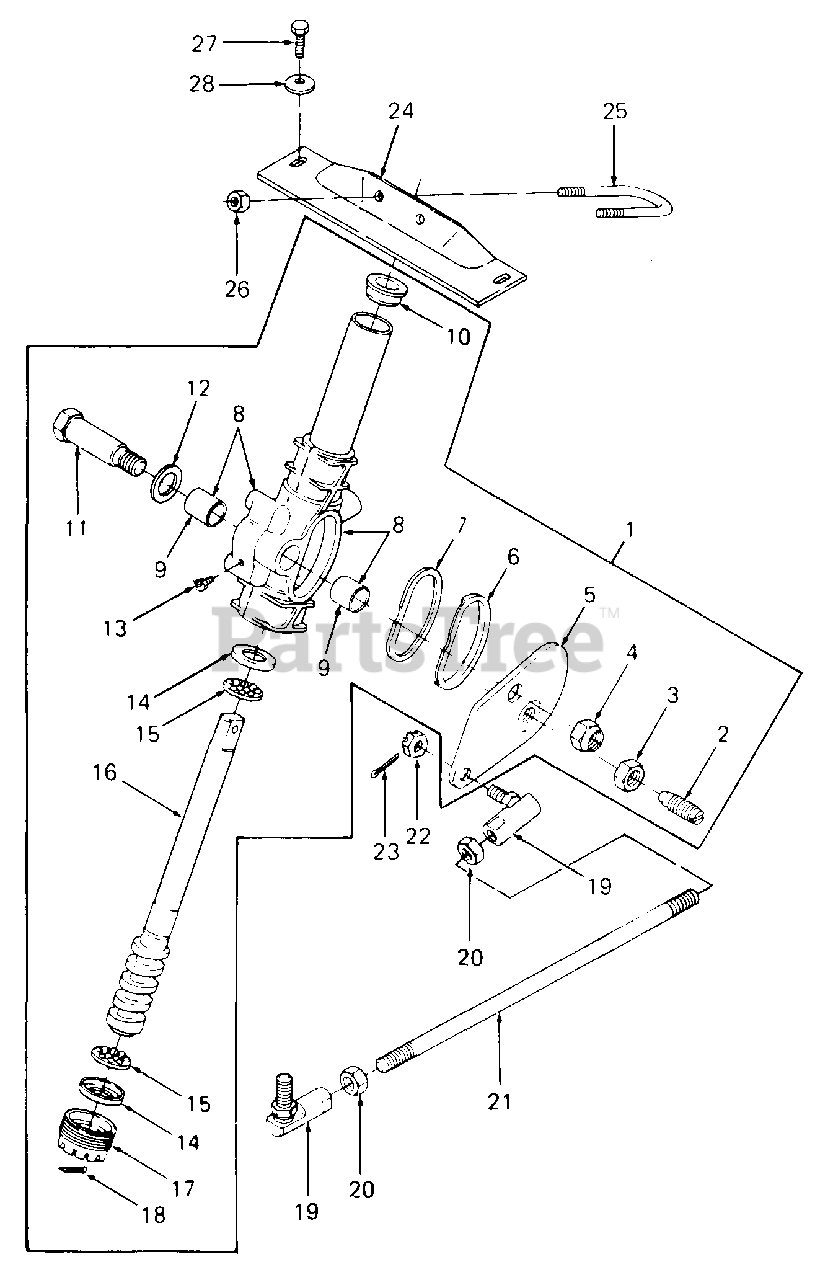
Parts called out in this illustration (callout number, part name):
1	Steering Gear Assy
2	Follower, Cam
3	Nut, Hex Jam, 9/16-18
4	Nut, Hex Crown Lock, 5/8-18
5	Arm, Steering
6	Retainer, Seal
7	Seal
8	Housing/Tube Assy
10	Bearing, Column
11	Shaft, Pivot
12	Washer, Flat, .781 X 1.25 X .027 Thk
13	Fitting, Lube, 45 Deg 1/4-28 Taper
14	Cup, Bearing
15	Retainer Assy, Ball
16	Shaft/Cam Assy
17	Plug, Adjusting
18	Pin, Cotter, 1/8 Dia X .75 Lg
19	Ball Joint
20	Nut, Hex Jam, 1/2-20 GR5
21	Link, Drag
22	Nut, Hex Castle, 1/2-20 GR5
23	Pin, Cotter, 3/32 Dia X 1.25 Lg
24	Plate, Steering Support
26	Nut, Hex Center Lock, 5/16-24
27	Screw, Hex Hd Cutting, 5/16-18 X .75 Lg GR5
28	Washer, Bell, .345 X .88 X .060 Thk
